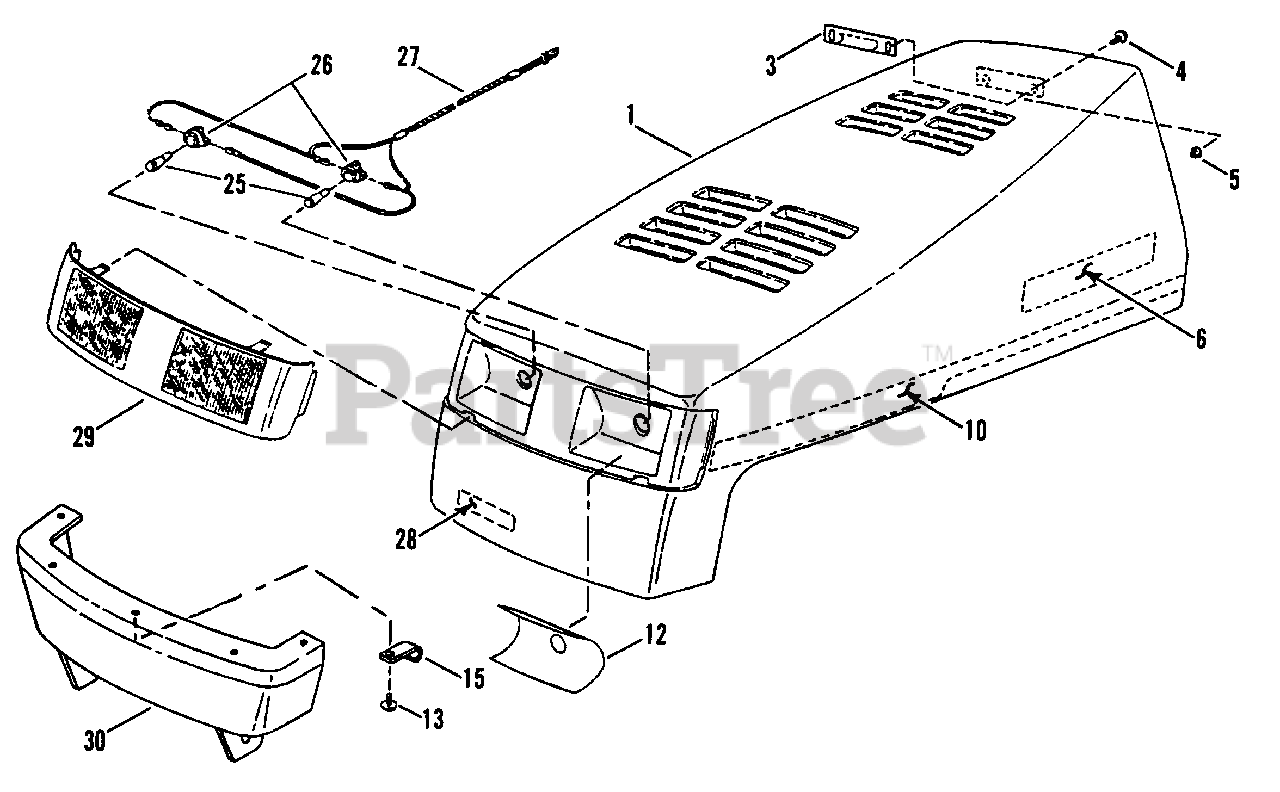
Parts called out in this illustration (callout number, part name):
1	HOOD
3	LATCH, Spring
4	SCREW, 1/4-20 x 5/8" Truss Head, Torx
5	NUT, 1/4-20 Hex Nyloc
6	DECAL - SNAPPER, 8" Molded Logo, White Letters
6	DECAL - SNAPPER, 8" Molded Logo, Silver Letters
10	DECAL, Hood (Right Hand)
10	DECAL, Hood (Left Hand)
10	DECAL, Hood (Right Side)
10	DECAL, Hood (Left Side Shown)
12	DECAL, Clear Lens (Left Hand)
13	SCREW, M4.8 x 1.59 x 16.00MM, Special
15	CLIP, "J"
25	BULB, Headlights
26	SOCKET, Headlight Bulb
27	HARNESS, Headlight Wiring
28	DECAL - SNAPPER, 4" Molded Logo
29	LENS, Solid Black
29	LENS, Clear
30	BUMPER, Front Hood Support
